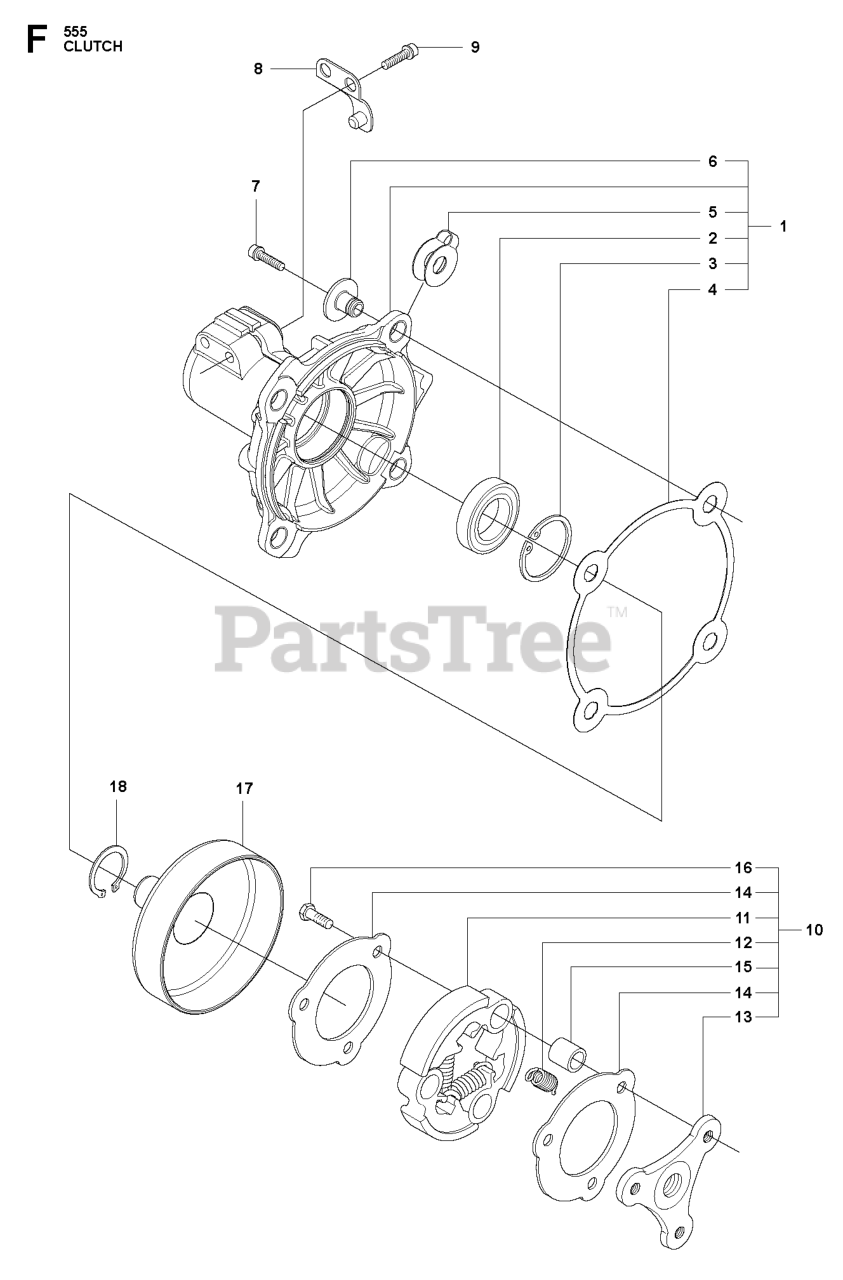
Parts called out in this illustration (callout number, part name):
1	CLUTCH COVER ASSY
2	BALL BEARING 6202-2RS1
3	RETAINING RING SGH 35
4	WASHER
5	SPRING PLATE
6	SPACING SLEEVE
8	LOCKING PLATE
10	CLUTCH ASSY
11	CLUTCH SHOE
12	CLUTCH SPRING
13	CLUTCH HUB
14	WASHER
15	BUSHING
16	SCREW
17	CLUTCH DRUM
18	RETAINING RING SGA 15
